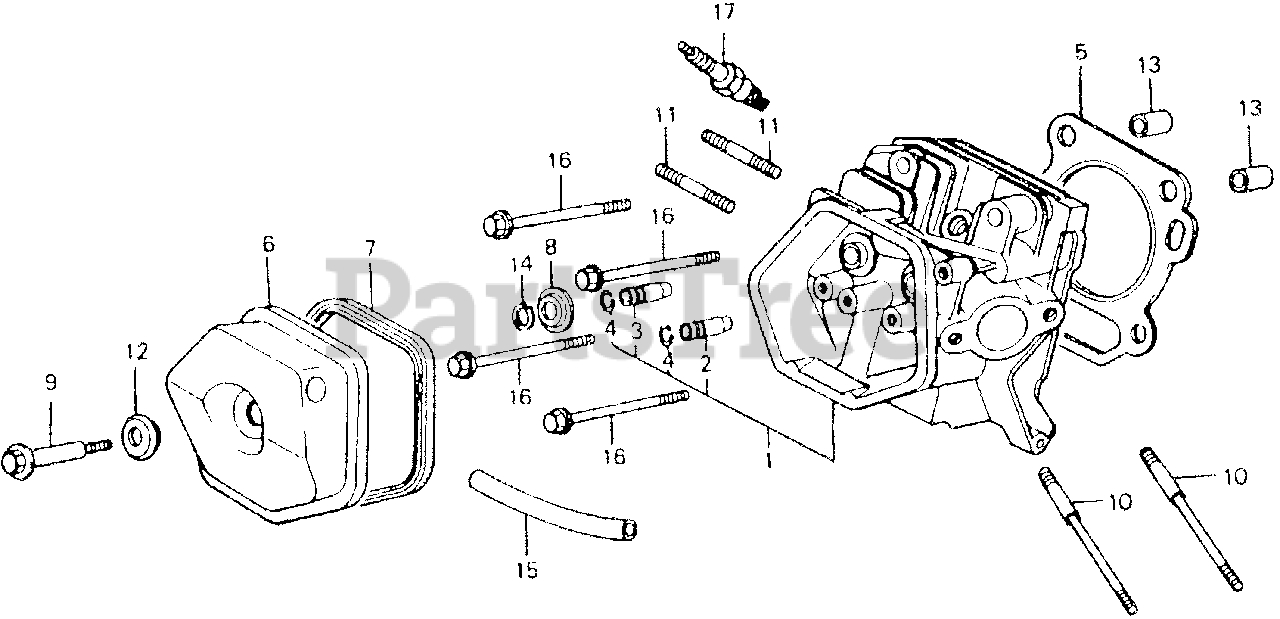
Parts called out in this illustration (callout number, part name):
1	CYLINDER HEAD
2	GUIDE, VALVE (OS)
3	GUIDE, EX. VALVE (OS)
4	CLIP, VALVE GUIDE
5	GASKET, CYLINDER HEAD
6	COVER KIT, HEAD
7	GASKET, CYLINDER HEAD COVER
8	SEAT, VALVE SPRING
9	BOLT, HEAD COVER
10	BOLT, STUD (8X123)
11	BOLT, STUD
11	BOLT 2, STUD (8X32)
12	WASHER, HEAD COVER
13	PIN A, DOWEL (12X20)
14	CIRCLIP (OUTER) (11MM)
15	BULK HOSE, VACUUM (11X1000) (11X105)
16	BOLT, FLANGE (10X80)
17	SPARK PLUG (BPR5ES) (NGK)
17	SPARK PLUG (W16EPR-U) (DENSO)
17	SPARK PLUG (BPR6ES) (NGK)
17	SPARK PLUG (W20EPR-U) (DENSO)
